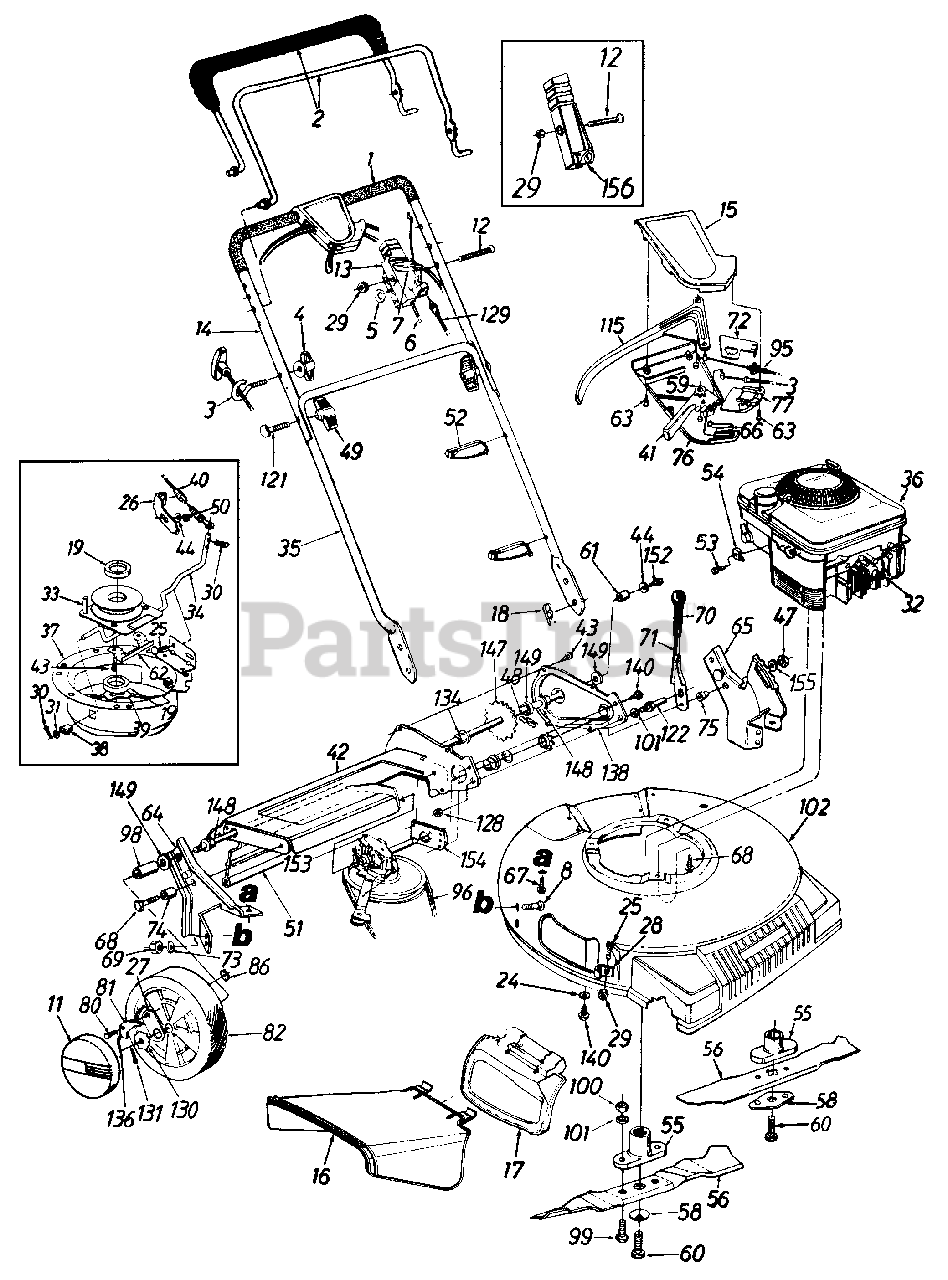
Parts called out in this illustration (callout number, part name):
1	Grip
3	Rope Guide
4	Handle Knob 1/4-20 Thd.
5	Curved Spring Wash. .66" I.D.
6	Throttle Wire - 55" Lg.
7	Throttle Lever
8	Carriage Bolt 5/16-18 x .62" Lg.
11	Hub Cap
12	Oval C-Sunk Mach. Scr.
13	Throttle Body
15	Upper Control Housing
16	Side Chute Deflector
18	Internal Cotter Pin 5/16" Dia.
19	Spacer .88" I.D.
24	Bell-Wash. .265" I.D. x .75" O.D.
25	Carriage Bolt 1/4-20 x .5" Lg.
30	Cotter Pin 3/32" Dia. x .75"
31	Fl-Wash. .328" I.D. x .68"
32	Spark Plug Insulator
33	Pulley Ass'y.
34	Shift Rod
36	Engine
39	Wave Washer .88" I.D.
40	6 Spd. Cable
41	6 Spd. Shift Lever
44	Bell-Wash. 1/4" I.D.
47	Hex Patch L-Nut 3/8-24 Thd.
48	#48 Chain .500" Pitch x 38 Links
49	Hand Knob
50	Hex L-Nut 1/4-20 Thd.
51	Rear Flap 4.8" x 17.5" Lg.
52	Cable Tie
53	Hex Wash. Hd. Scr. #10-32 x .62" Lg.
54	Casing Clamp
55	Blade Adapter
56	21" Mulching Blade
58	Bell-Wash. .39" I.D. x 1.14" O.D.
59	Gear Insert
60	Hex Bolt 3/8-24 x 2.5" Lg. (Gr. 8)
61	Spacer .513" I.D.
67	Hex B-Tap Scr. 5/16-18
68	Hex TT-Tap Scr. 3/8-16
69	Hex Nut 5/16-18 Thd.
71	Height Adj. Lever
72	6 Spd. Rack Cable Brkt.
73	Bell-Wash. 5/16" I.D.
74	Spacer .383" I.D.
75	Shld. Spacer .5" Dia.
76	Lower Control Housing
77	Cable Mounting Cap
80	Shld. Scr. .342" Dia. x .268
81	Pawl - R.H.
82	Wheel Ass'y. Comp. (Gray Rim)
86	Weld Top L-Nut 1/4-20 Thd.
95	S.P. Cable
96	"V"-Belt
98	Sleeve .526" I.D.
99	Hex Bolt 3/8-24 x 1.0" Lg.
100	Hex Nut 3/8-24 Thd.
101	L-Wash. 3/8" I.D.
121	Curved Hd. Bolt 5/16-18 x 2" Lg.
122	Shld. Pin 1.43" Lg.
128	Hex Jam Nut 3/8-24 Thd.
129	Control Cable - 39"
130	Ratchet Wheel 1.62" O.D.
131	Cotter Pin 1/8" Dia. x 1"
134	Hex Flange Bearing
136	Spring - Nylon
147	Rear Shaft Ass'y. 21.44" Lg.
148	Hex Flange Brg. .506" I.D.
149	Fl-Wash. .531" I.D. x .930"
152	Hex Bolt 1/4-20 x .62" Lg. (Gr. 5)
153	Transmission Comp. (See Breakdown)
155	Fl-Wash. .385" I.D. X .87" O.D.
156	Control Housing
